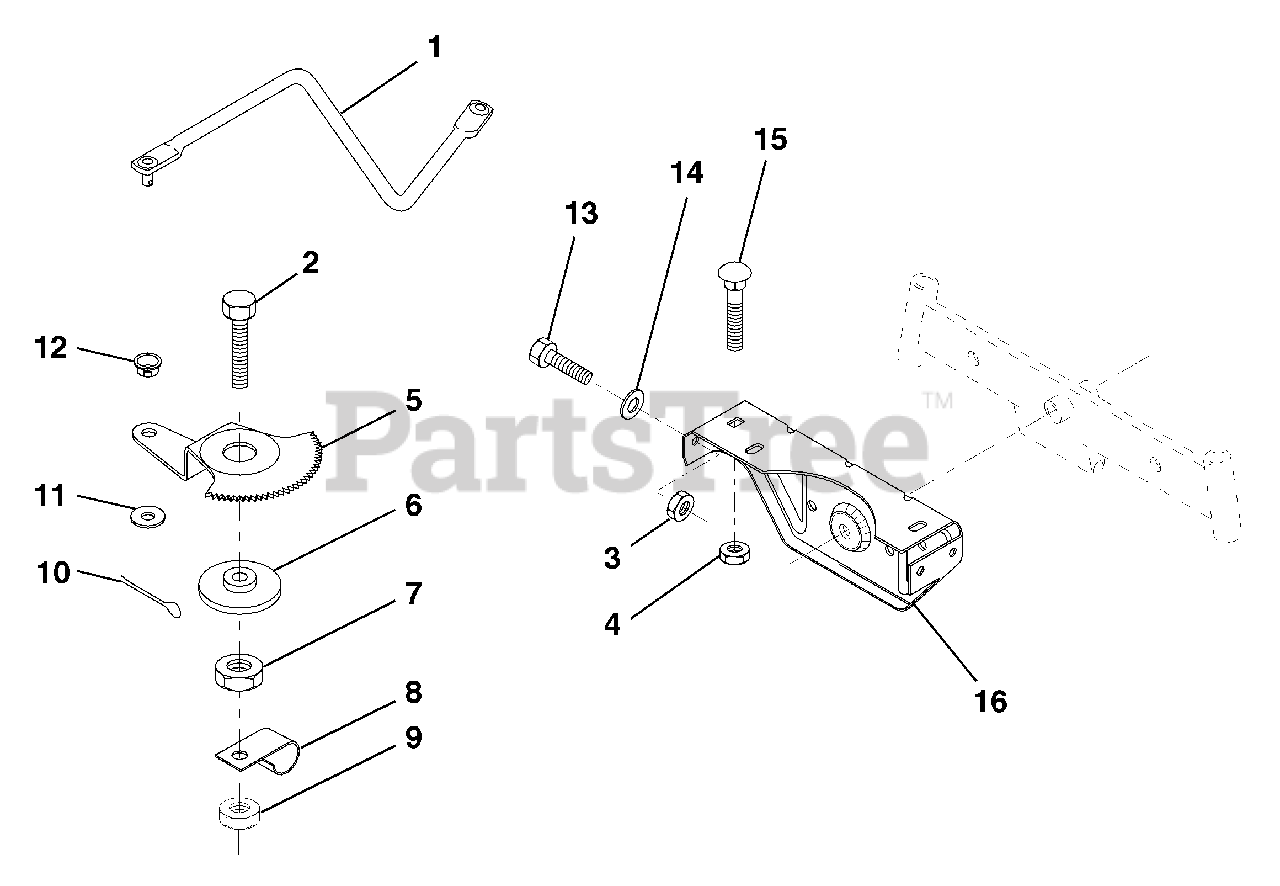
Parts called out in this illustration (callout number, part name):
1	Link, Drag
2	Bolt, Fin Hex 1/2-13 x 1-3/4
3	Nut, Crownlock 5/16-18
4	Nut, Crownlock 3/8-16 UNC
5	Gear, Sector
7	Nut, Heavy Hex Top Lock 1/2-13 UNC
8	Clip, Insulated
9	Nut, Crownlock 3/8-16
10	Pin, Cotter 1/8 x 3/4
11	Washer, 13/32 x 13/16 x 16 Ga.
13	Bolt, Hex Hd. 5/16-18 UNC x 3/4
14	Washer 11/32 x 7/8 x 16 Ga.
15	Bolt, Carriage 3/8-16 UNC x 3/4
16	Support, Front Axle
